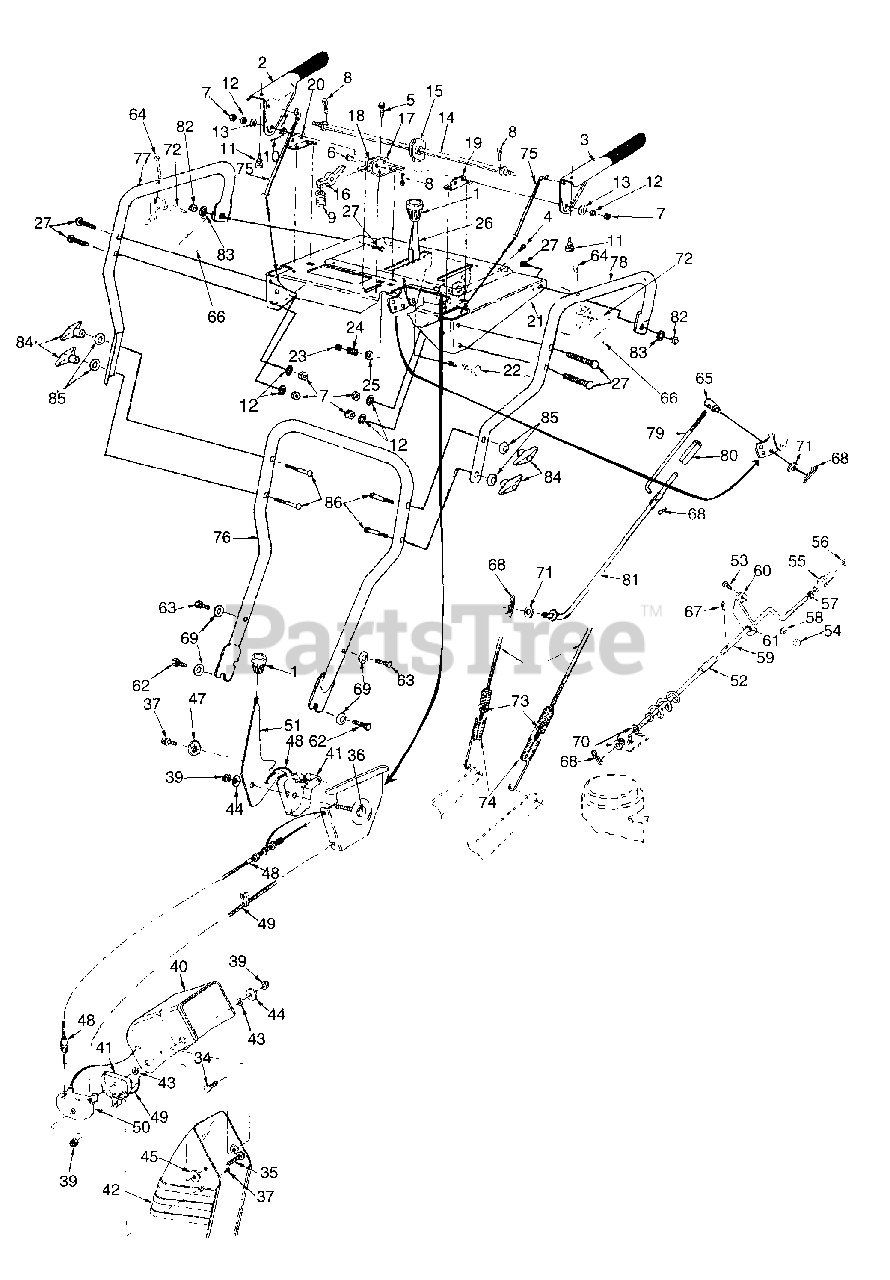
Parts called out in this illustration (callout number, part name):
1	Sml Shift Knob 1.6 Dia Sentar
2	Engage Handle Le Blk Dip Rh
3	Engage Handle Lf Blk Dip Lh
4	Pan Head B-tapp Scr #10 x .5
5	Hwhd Sf-tap Scr 1/4-20 x 1/2 Zn
6	Clevis Pin 31 Dia x 1.0
7	Nut Hex 5/16-18 Gd 5
8	Cot-pin 3/32 Dia x 1.0
9	Comp Spring 36 Dia x 1.0 Lg
10	Spring Torsion .44 ID
11	Rubber Bumper .63 Dia
12	Lock Washer 5/16
13	Wsher Spcl .345 Sq x .72 OD
15	Clutch Lock Cam
16	Clutch Lock Pawl
22	Scr Hex Cap 3/8-24 x 1.5 Gd 5
23	Hex Ins L-nut 3/8-24
24	Compression Spring 39 ID x .88
25	Bell Wash 40 ID x 88 OD x .06
34	Carriage Bolt 5/16-18 x 1.00
35	Carriage Bolt 5/16-18 x 1.75
36	Hex Scr 5/16-18 x 1.5
37	HWHD B Tapp Scr 1/4 x 5/8 Zn
39	Hex Ins L-nut 5/16-18
40	6" Upper Chute Remote Tilt
41	Chute Tilt Cable Guide
42	6" Lower Chute Remote Tilt
43	Chute Pivot Spacer
44	Fl-wash 344 ID x 88 OD x .063
45	Flt Wshr 344 x 1 125 x .125
47	Contoured Washer
48	Chute Control Cable 66"
49	Chute Control Cable 66" W/clip
54	Hex Nut 1/4-20
55	Chute Crank Knob Countersink
56	Push Cap 3/8 Palnut #375011
57	Flat Washer 38 ID x 60 OD x .033
58	Bell Wash 26 ID x 75OD x .06T
61	Plastic Bushing .380 ID
62	Hex Scr 3/8-16 x .75
63	Hex Scr 3/8-16 x 1.75
64	Scr Oval C/sunk #10-24 x 1.75
65	Adjustment Ferrule
66	#10-24 Flat Weld Nut
67	Internal Cot-pin 1/2 Dia
68	Inter Cot-pin 5/16 Dia
69	Bell Wash 4 ID x 88 OD x .06
70	Fl-wash 406 ID x 74 OD x .063
71	Fl-wash Sae 34 x 68 x .062
72	Trigger Ass'y Steer
73	Hex Ins L-nut 1/4-20
74	Extension Spring
75	Cable Clutch Drive
79	Upper Shift Rod 5/16 x 10.57
80	2 Pc Shift Rod Connector
81	Lower Shift Rod 3/8 x 14.75
82	Hex Nut 1/4 - 20
83	Bell Wash 26 ID x 75 OD x 06T
85	Bell Wash 345 ID x 88 OD x .060
86	Carriage Bolt 5/16 -18 x 2.5
